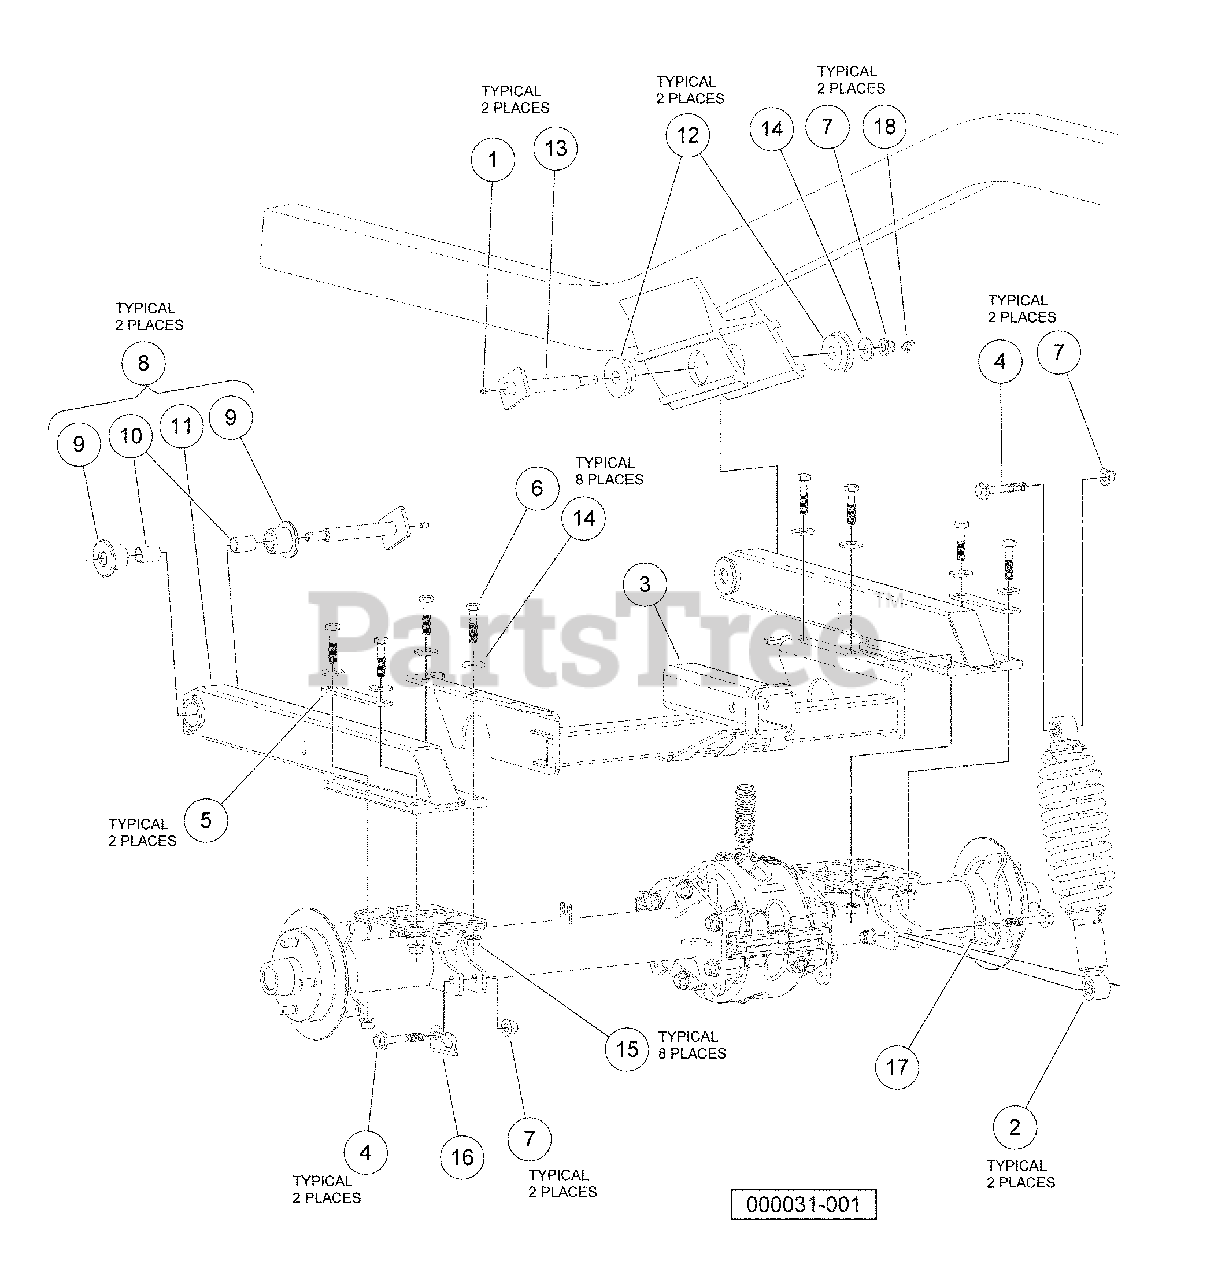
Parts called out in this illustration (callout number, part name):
1	Fitting, 1/4-28 Thread-Forming Grease
2	Shock, Coil Over, Rear HD
3	Weldment, Receiver, Rear
4	Bolt, Flange Head, M12 X 1.75 X 70
5	Washer, Strip, Swingarm
6	Bolt Flanged Head, M12 X 1.75 X 50
7	Nut Flg, M12x1.75, Nylon Gr 10
8	Sub Asm Swingarm
9	Bushing, Pivot, Urethane
10	Bushing, Teflon
11	Swingarm, Rear, Awd
12	Insert, Flanged, H-Bracket
13	Pin, Swingarm, Weldment
14	Washer, M12 Hard Regular
15	Nut Flg M12 X 1.75 Cl10
16	Brkt, Line, Hyd, Shk Mnt, Drv.
17	Brkt, Line, Hyd, Shk Mnt, Pass
18	Cotter, Rue Ring, 1/2".
